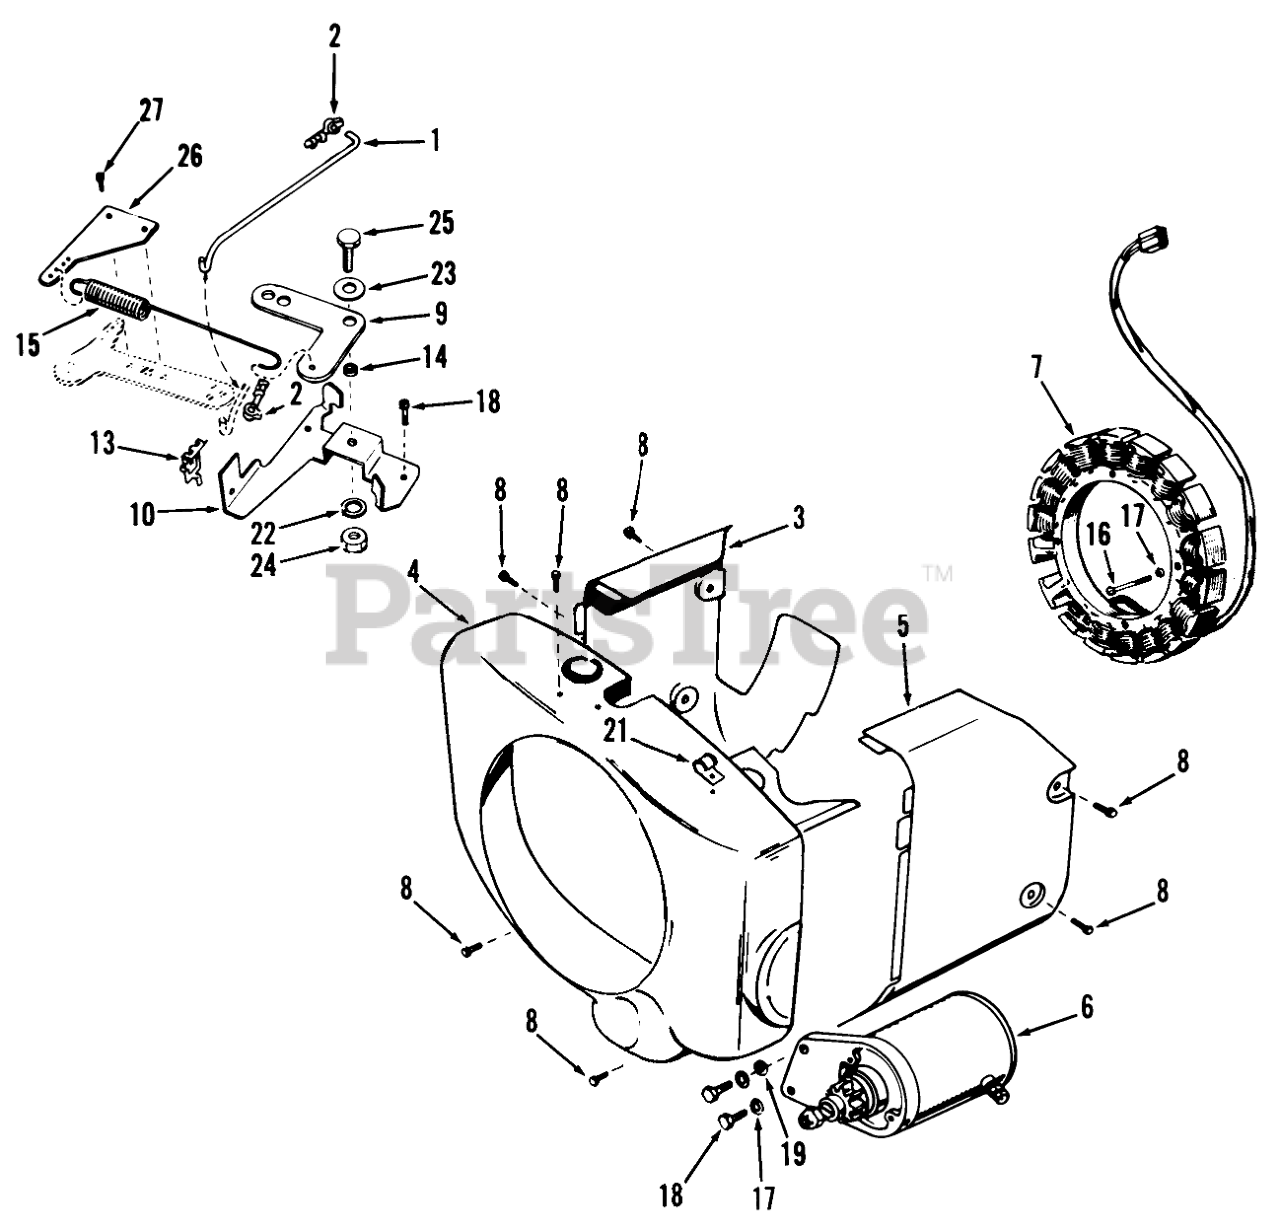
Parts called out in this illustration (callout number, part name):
1	ROD-GOV CONTROL
2	GOV END-CONTROL ROD
2	Carburetor End
3	Shroud-Left Side
4	Blower Housing
5	Shroud-Right Side
7	Alternator Stator
8	Bolt 1/4-20 X 7/16
9	Governor Control Arm
10	Governor Mounting Bracket
14	Governor Control Bushing
15	Governor Spring
16	Round HD Screw 10-32 X 1 1/2
17	Lockwasher 5/16 Starter
17	Stator Mounting (#10)
18	Hex Bolt #8 X 3/8 Governor
18	Hex Bolt 5/16-18 Starter
19	Washer-Starter-Top Hole
21	Clip-Fuel Hose
22	Lockwasher 1/4
23	Washer
24	Nut 1/4-20
25	Hex Bolt
26	ADAPTOR-GOV ARM
27	Screw 10-32 X 1/2
